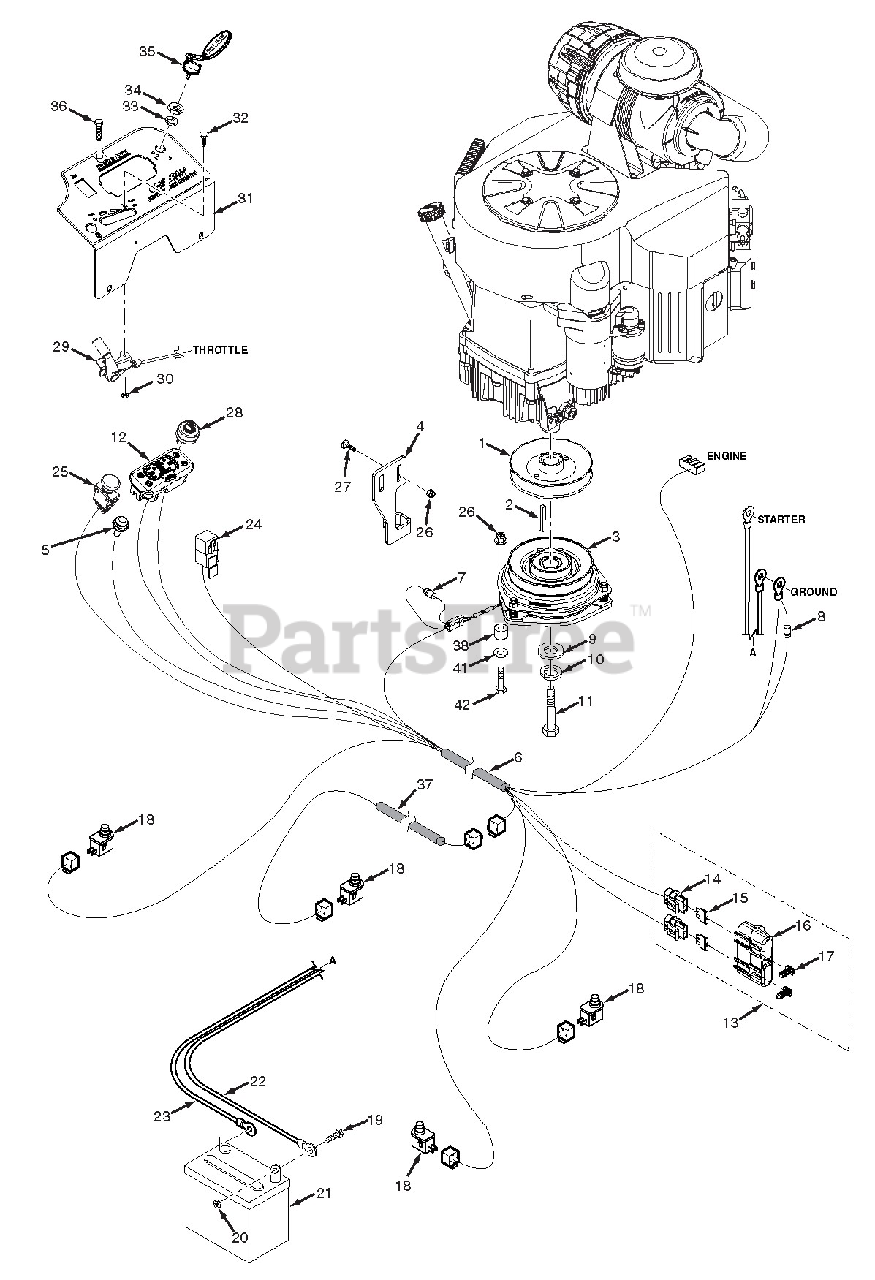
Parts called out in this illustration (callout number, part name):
1	Pulley, 5.80 Dia. - 1.125 Bore
2	Key, 1/4 x 1/4 x 3-1/4"
3	Electric Clutch w/Tag - GT-5 (ECV860, ECV940)
4	Bracket, Anti-Rotation
5	Indicator Light Assembly
6	Wire Harness, SCZ-EFI
7	Diode, 600V - 6A
8	Diode
9	Flatwasher, 7/16-.469 x 1.75 x .25
10	Lockwasher, 7/16" Spring
11	Bolt, Hex Head 7/16-20 x 2-1/4" w/Patch
12	Tiger Eye Cluster Gauge
13	Double Fuse Assembky
14	Fuse Holder
15	Fuse, 20 Amp
16	Cover, Sealed Double
17	Clip, Wire
18	Switch, N.O.
19	Bolt, Hex Head 1/4-20 x 1/2"
20	Nut, 1/4-20
21	Battery
22	Battery Cable, 18" Black
23	Battery Cable, 25" Red
24	Relay
25	Switch, PTO - 10 Amp
26	Nut, FLF HH Elastic Stop 5/16-18
27	Bolt, Carriage 5/16-18 x 1"
28	Keyswitch w/Hardware
29	Control Cable
30	Nut, Elastic Stop #10-24
31	Instrument Panel w/Decal
32	Bolt, Carriage #10-24 x 1/2"
33	Lockwasher, 5/8" Internal
34	Nut, Hex 5/8-32
35	Key, Ignition
35	Key Assembly w/Fob
36	Bolt, Hex Head 1/4-20 x 1/2" Serrated Flange
37	Wire Harness, Operator Platform -SCZ
38	Bushing, UHMW
39	Nut, FLF HH Elastic Stop 5/16-18
40	Bolt, Carriage 5/16-18 x 1"
41	Flatwasher, 5/16-.375 x .875 x .083
42	Bolt, Hex Head 5/16-18 x 1-1/2"
